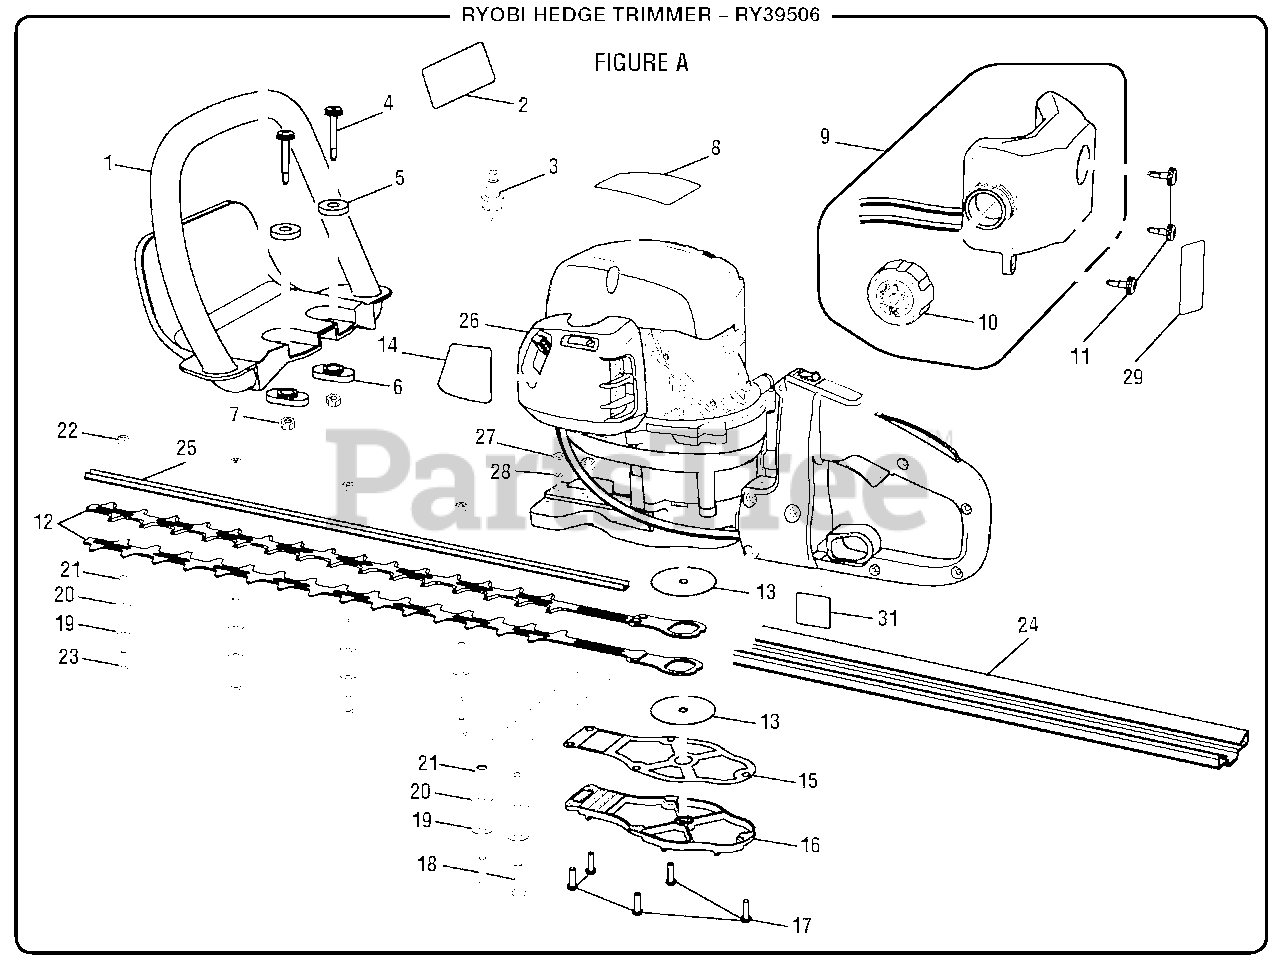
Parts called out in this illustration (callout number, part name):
1	Front Handle Guard
2	Warning Label
3	Spark Plug (L7RTC Torch)
4	Screw (M5 x 26 mm)
7	Lock Nut (M5 x 0.8 mm)
8	Logo Label
9	Fuel Tank Assembly
11	Screw (M4)
12	Blade Assembly
14	Starting Label
16	Gear Box Cover
17	Screw (M5 x 18 mm)
18	Screw (M6 x 26 mm)
22	Lock Nut (M6)
23	Screw (M6 x 17 mm)
25	Blade Top Strap
26	Air Box Cover
27	Lock Nut (M6)
28	Spring Washer
29	Gas Tank Warning Label
30	Combustion Warning Label
31	Indicator Label
